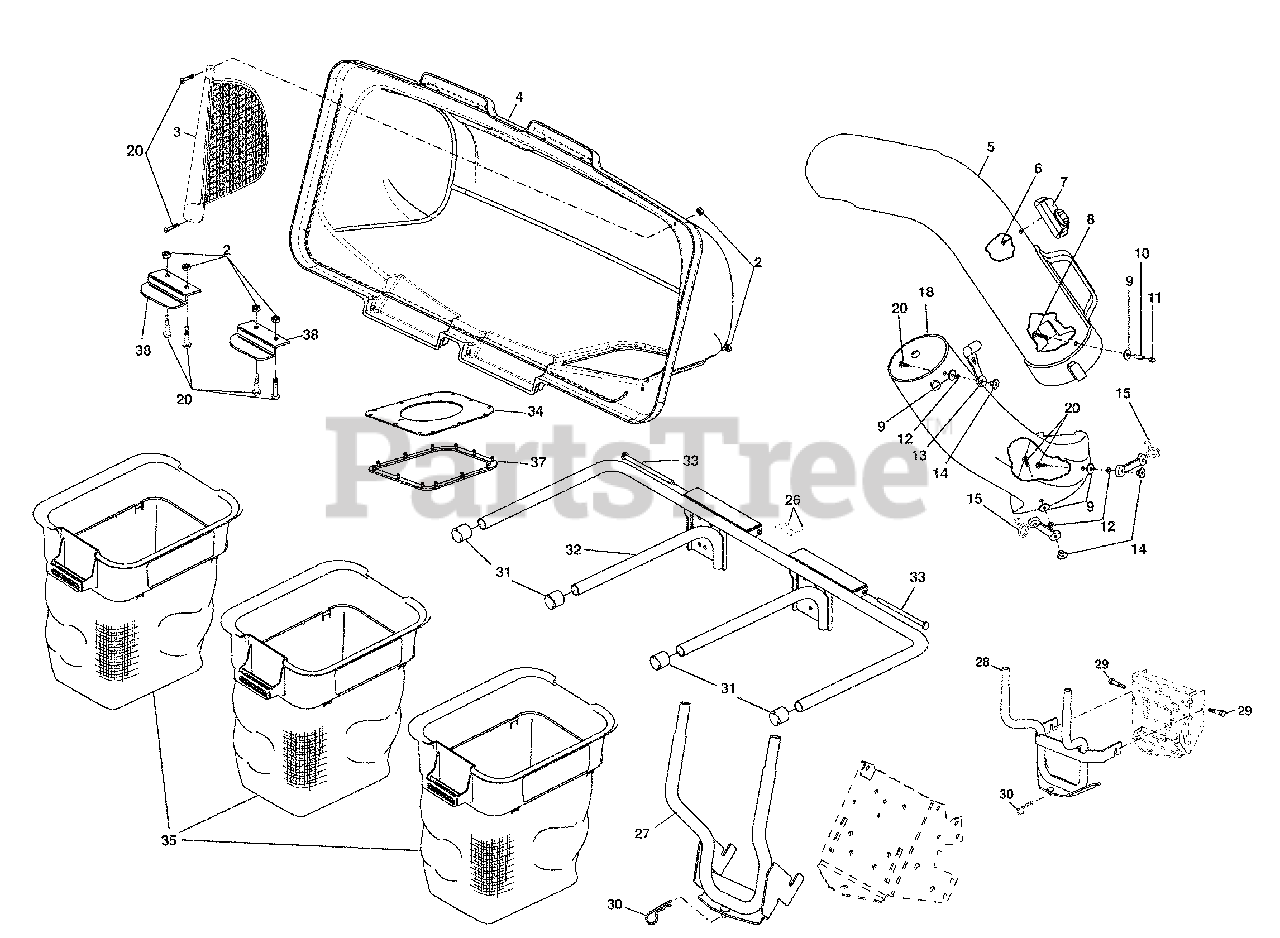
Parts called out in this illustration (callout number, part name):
2	Nut, Crown lock #10-24
3	Screen, Cover
4	Cover Assembly
5	Chute, Upper
6	Screw, Special #10-14 x 1/2
7	Full Bag Indicator
8	Screw, #10-24 x 1-1/8
9	Washer 3/16 x 3/4 x 16 Ga.
10	Spacer, Split
11	Nut, Acorn #10-24
12	Washer, lock
13	Latch, Chute
14	Nut, Weld
15	Latch
18	Chute, Lower
20	Screw #10-24 x 5/8
26	Spring, Retainer
27	Support Assembly
28	Support Assembly
29	Shoulder Bolt
30	Spring, Retainer
31	Plug, Tubing End
32	Bagger, Frame
33	Pin, Hinge
34	Gasket, Cover
37	Seal, Cover
38	Latch Handle, Cover
